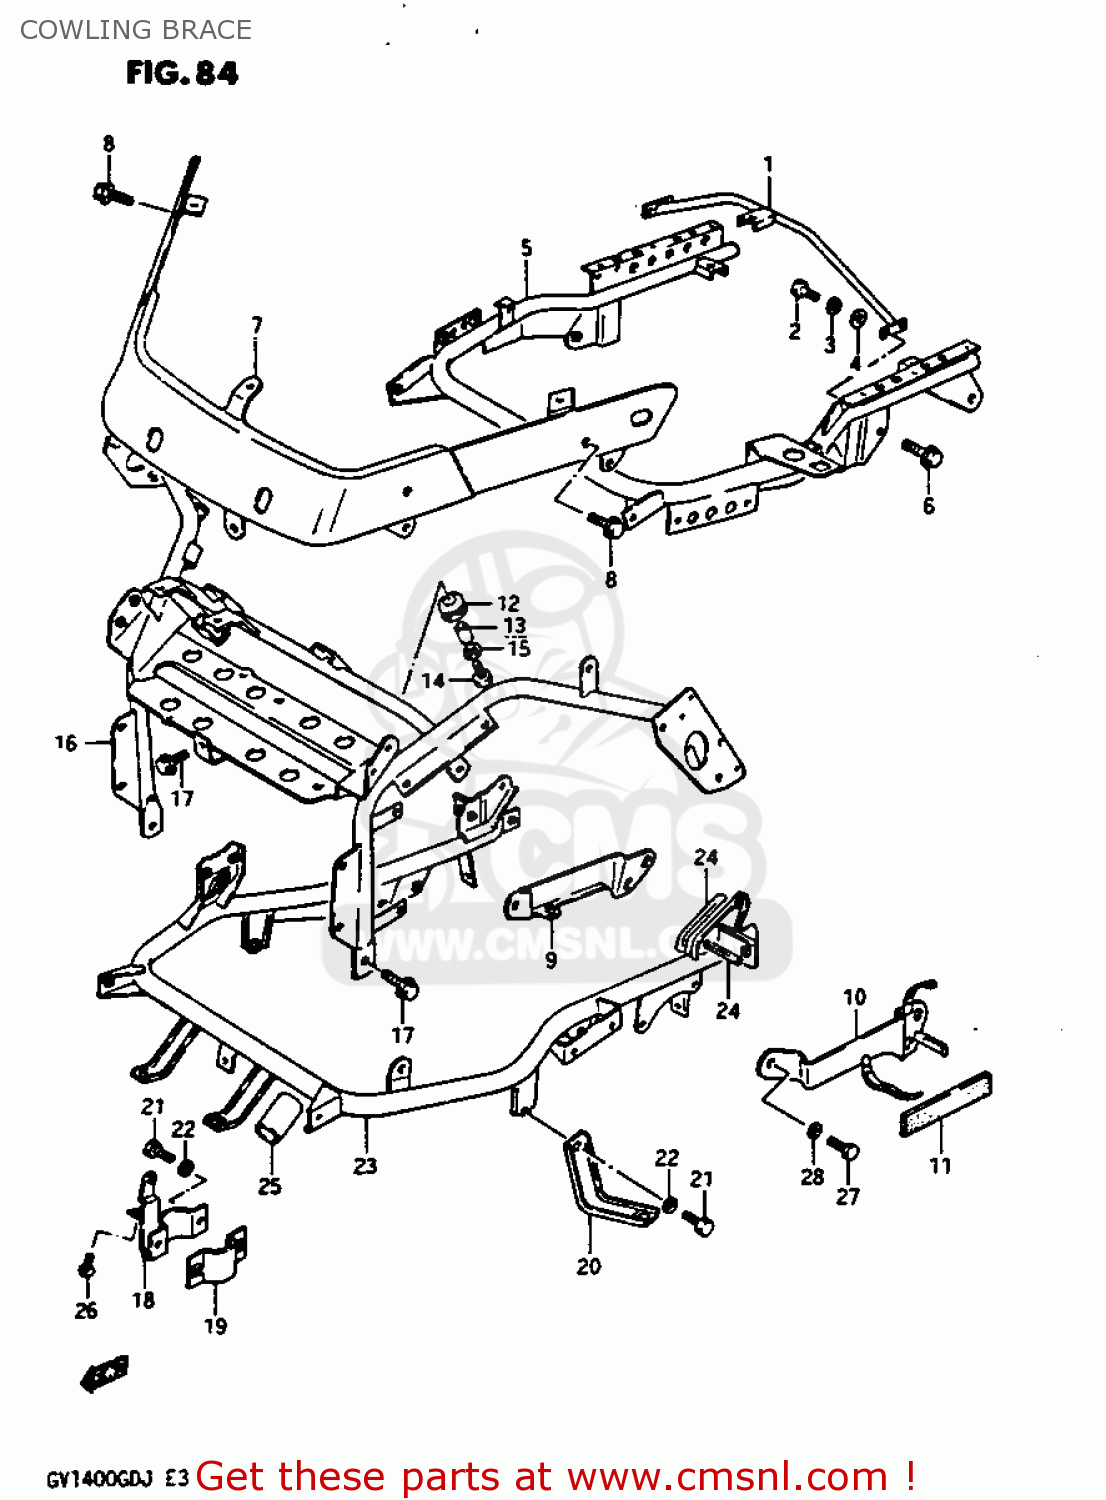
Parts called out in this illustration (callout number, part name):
1	BRACE,CENTER COVER
2	BOLT
3	LOCK WASHER
4	WASHER,5.5X12X
5	BRACE,UPPER
6	BOLT
7	BRACE,SCREEN
8	BOLT
9	REINFORCEMENT,RIGHT
10	REINFORCEMENT,LEFT
11	CUSHION
12	CUSHION
13	SPACER (6.1X8X9.5)
14	BOLT 6X16
15	WASHER (6.5X22X1.6)
16	BRACE,HEADLAMP
17	BOLT
18	BRACKET COMP,COWLING SIDE
19	BRACKET COMP,COWLING SIDE
20	BRACKET COMP,COWLING COVER
21	BOLT
22	WASHER,LOCK
23	BRACE COMP,REAR
24	MOLDING,FUEL TANK
25	PROTECTOR,REAR BRACE
26	SCREW
27	BOLT 6X16
28	WASHER (6.5X22X1.6)
